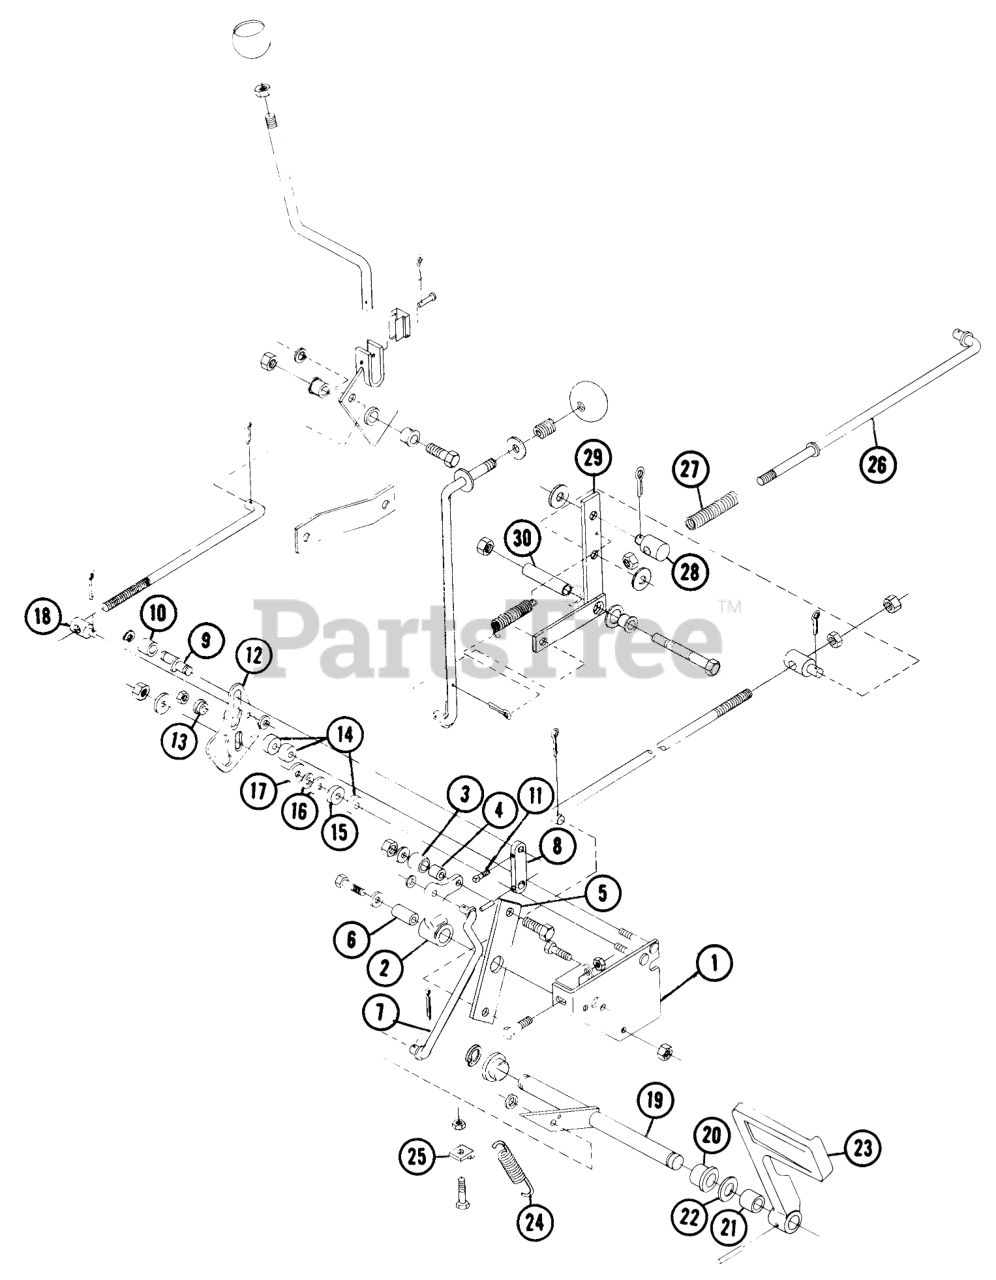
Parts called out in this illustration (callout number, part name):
1	Assy-Plate
2	Lever-Neutral Return
3	BEARING-CAM RETURN
4	SPACER
6	Spacer
7	ROD ASSY
8	Arm-Speed Control
9	ECCENTRIC-CAM FOLLOW
10	Spacer
11	SET SCREW
12	Cam-Speed Control
13	CAM-SPACER
14	Spacer
15	SPACER
16	WASHER-SPRING DISC
17	FRICTION WASHER
19	Assy-Shaft
20	BEARING
21	Spacer
22	WASHER
23	Brake Pedal
24	SPRING-EXTENSION
25	CLIP - SPRING
26	Assy-Rod
27	Spring
28	TRUNNION-LIFT
29	Assy-Arm Brake
30	Spacer
31	FLANGED BUSHING
32	Washer
33	Assy-Brake Rod
34	SPRING
35	SHIFT KNOB
36	Rod
37	TRUNNION-LIFT
38	SPRING-COMPRESSION
39	HANDLE
40	Spring
41	Clevis Pin
42	CAM-SPACER
43	FLANGED BUSHING
44	Brace
45	ASSY-PIVOT
